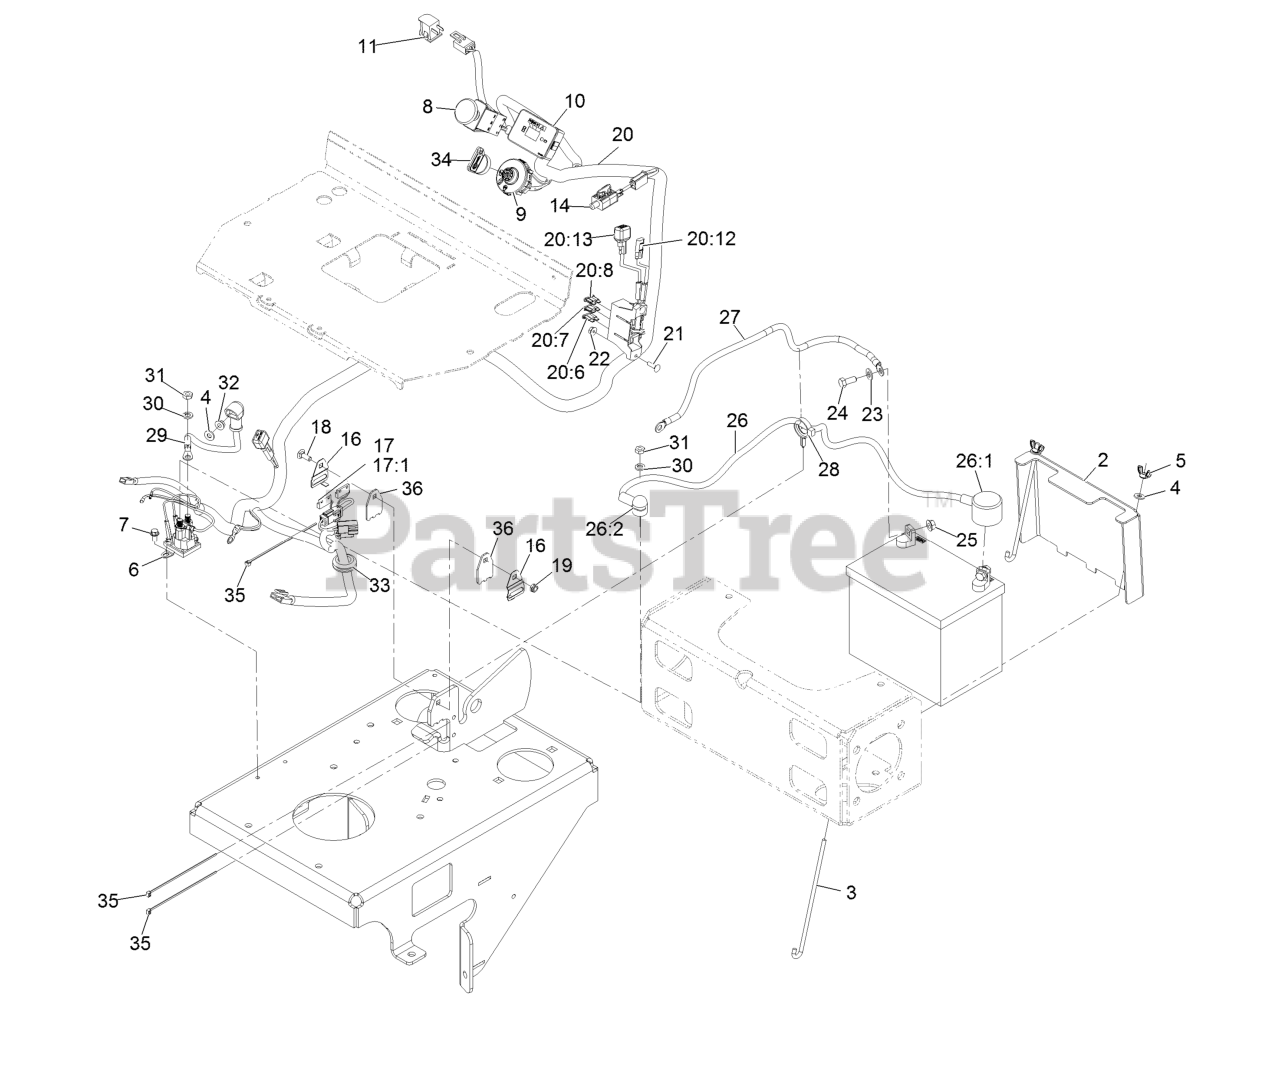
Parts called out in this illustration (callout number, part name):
2	Cover-Battery
3	Bolt-Holddown
4	Washer-1/4 SAE
5	Wingnut-Nyloc 1/4-20
6	Solenoid
7	Screw-HWH 1/4-20 X 1/2 Taptite
8	Switch-PTO, On-On-(On)
9	Switch-Ignition
10	Module-Hour Meter
14	Switch-Plunger, NC, Spst
16	Clamp-Switch
17	Harness-Switch, Reed
17:1	Harness-Wire, Reed Switch
18	Bolt-Carriage 1/4-20 X 3/4
19	Nut-Nyloc 1/4-20 Thin
20	Harness, Wire
20:6	Fuse-Blade, 30 Amp
20:7	Fuse-Blade, 25 Amp
20:8	Fuse-Blade, 10 Amp
20:12	Cap-Plug
21	Screw-CARR
22	Nut-Whizlock #10-24
23	Washer-5/16 SAE
24	Screw-HH 5/16-18 X 3/4
25	Nut-Hex Flange 5/16-18
26	Cable, Battery (+)
26:1	Insulator-Battery
26:2	Insulator-Solenoid
27	Cable-Battery, Negative
28	Clamp-Hose
29	Cable-Battery, Red
30	Washer-Lock 5/16
31	Nut-Jam 5/16-24
32	Nut-Whizlock 1/4-20
33	Grommet
34	Key-Exmark Logo
35	Tie-Cable 5 1/2 (Small)
36	Plate-Spacer
